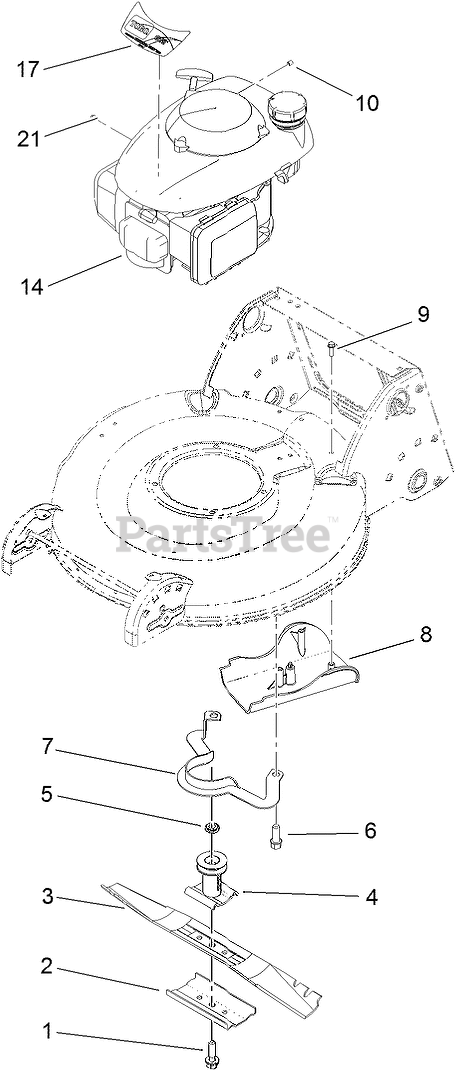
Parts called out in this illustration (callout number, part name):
1	BOLT-BLADE
2	SUPPORT-BLADE
3	BLADE-21 INCH
4	DRIVER-BLADE
5	Spacer-Driver
6	SCREW-TAPTITE
7	Guide-Belt
8	COVER-BELT
9	SCREW-HWH
10	STOP-ROPE
17	DECAL-ENGINE
21	SCREW-HWH
